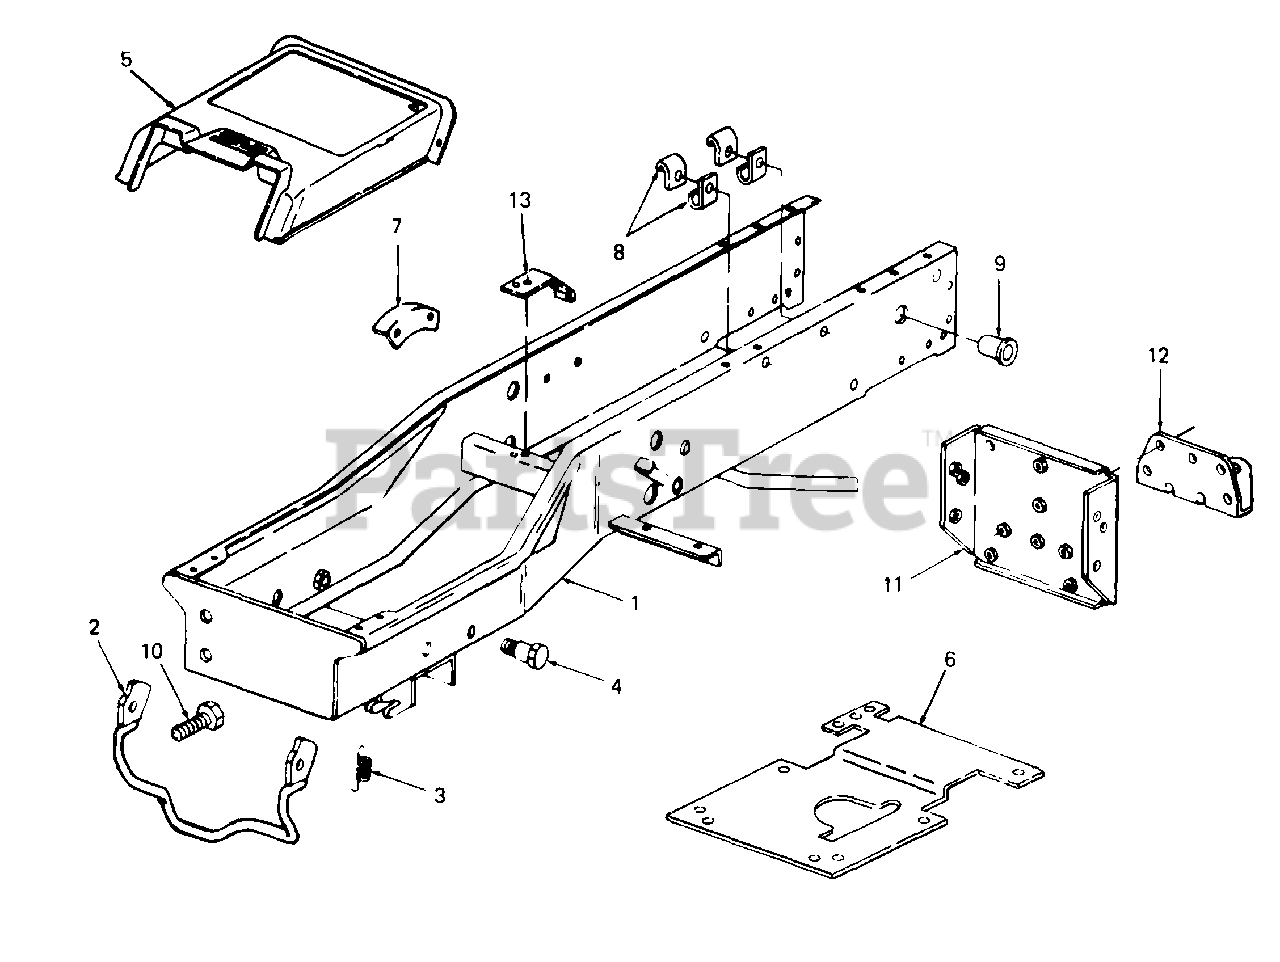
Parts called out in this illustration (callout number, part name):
3	Spring, Latch
4	Bolt, Shoulder
5	Cover, Frame
6	Baffle, Lower Frame
7	Bracket, Height Indicator
8	Clip, Cable
9	Bushing, Snap
10	Screw, Adjustment, 1/2-20 x 1.0 Lg GR5
13	Bracket, Switch
